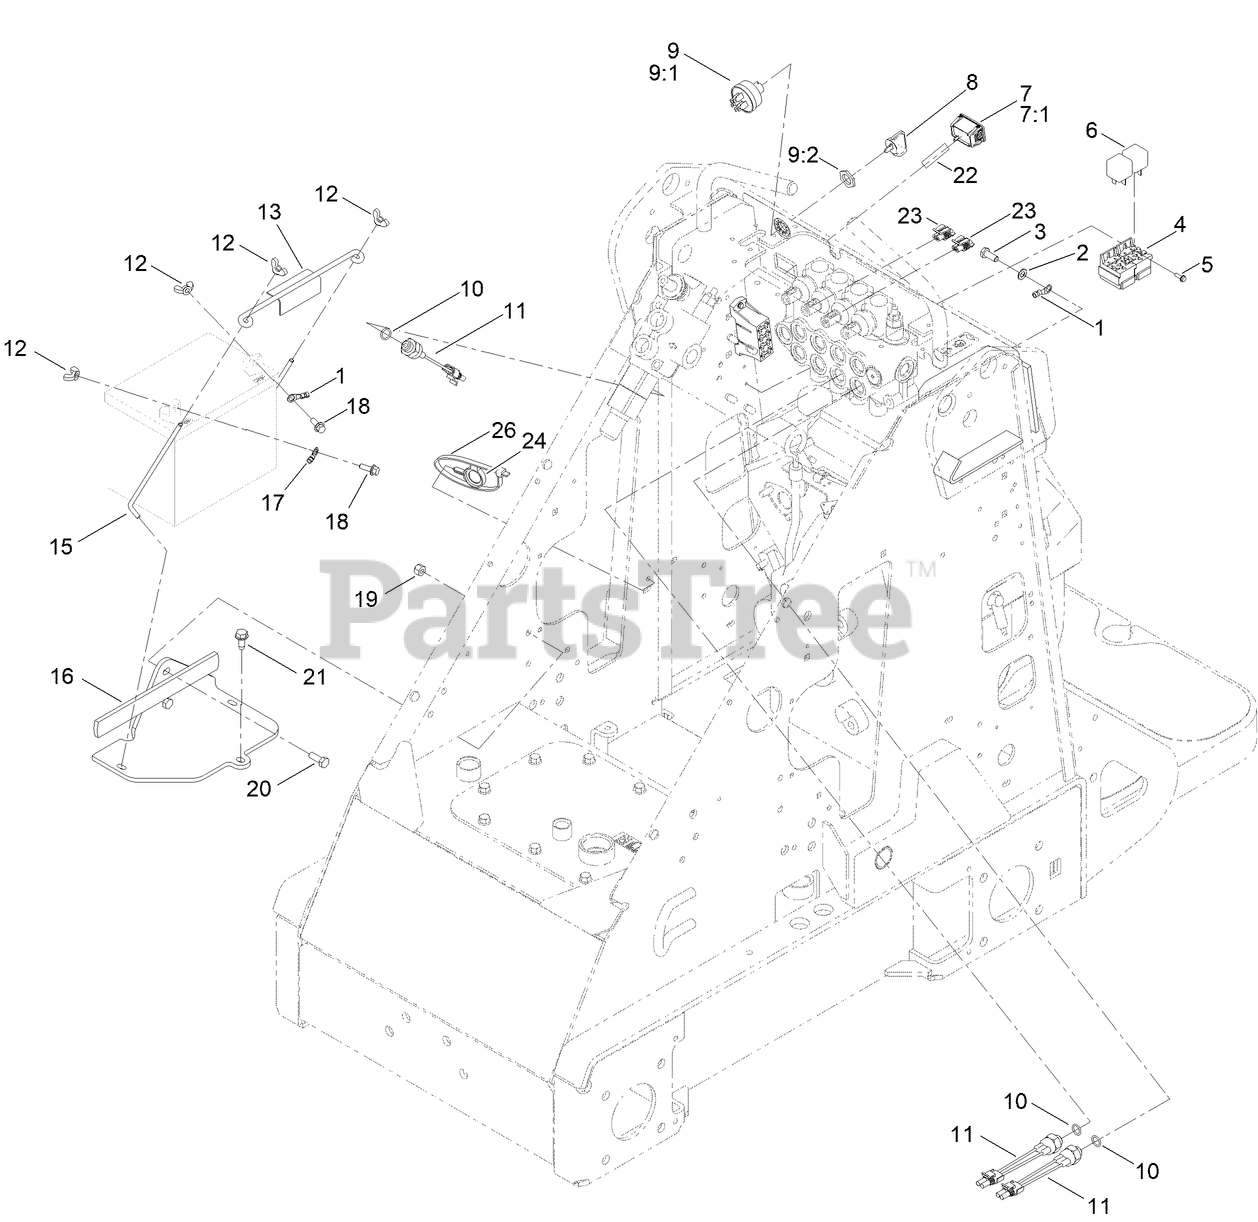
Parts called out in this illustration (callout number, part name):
1	WIRE ASM
2	WASHER-LOCK
3	SCREW-HH
4	HARNESS-WIRE
5	SCREW-HWHTF
6	RELAY
7	HOURMETER-INDUCTIVE
7:1	CLIP-MOUNTING
8	KEY-IGNITION
9:1	WASHER-LOCK
10	O-RING
11	SWITCH-BALL
12	NUT-WING
13	HOLDDOWN-BATTERY
15	RETAINER-BATTERY
16	BATTERY MOUNT ASM
17	CABLE-POSITIVE
18	SCREW-HHF
19	NUT-LOCK, NI
20	SCREW-HH
21	SCREW-HWHTF
22	WIRE-HOURMETER
23	CONNECTOR-FEMALE
24	CLIP-TIE
26	TIE-CABLE
